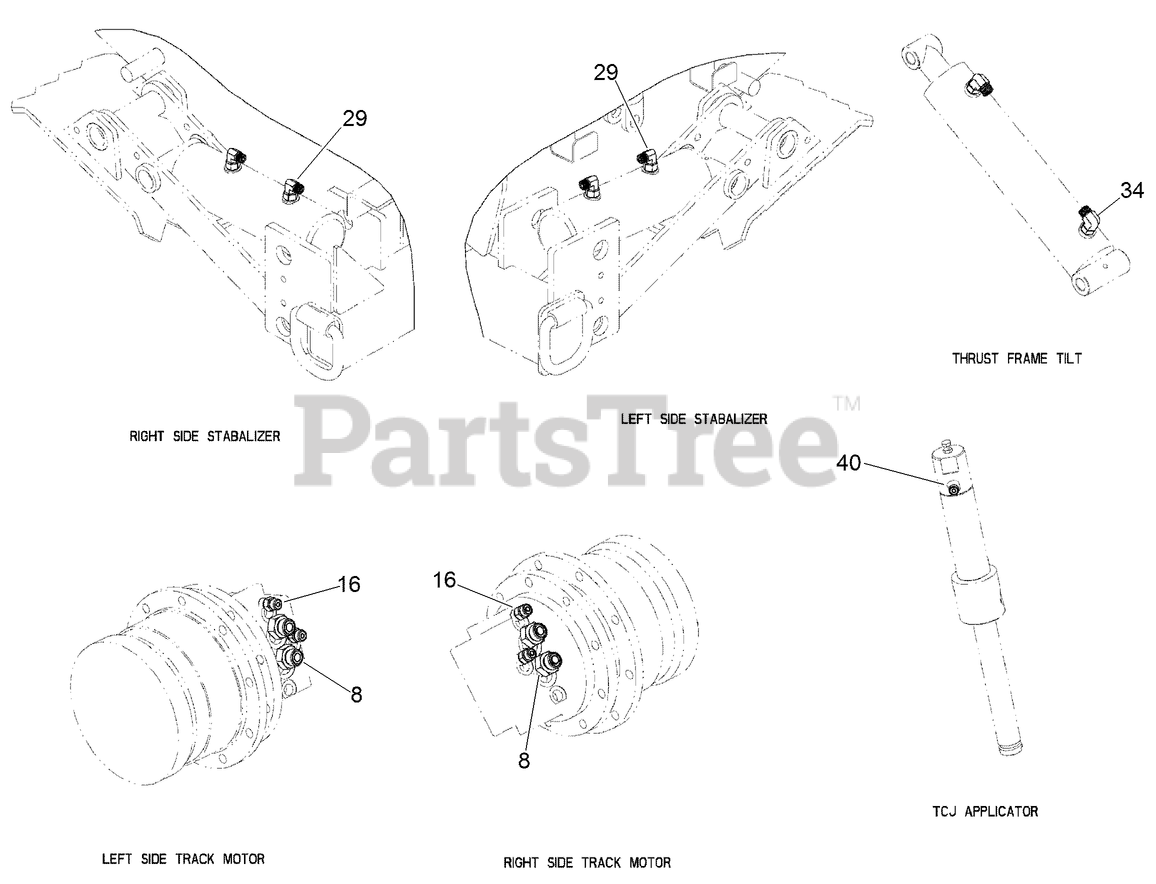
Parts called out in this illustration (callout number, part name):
8	CONNECTION - Straight, -8 ORFS / -10 ORB
16	CONNECTION - Straight, -4 ORFS / -6 ORB
29	CONNECTION - 90 Deg, -4 ORFS / -6 ORB
34	CONNECTION - 90 Deg, -6 ORFS / -6 ORB
40	CONNECTION - Straight, -4 ORFS / -4 ORB
